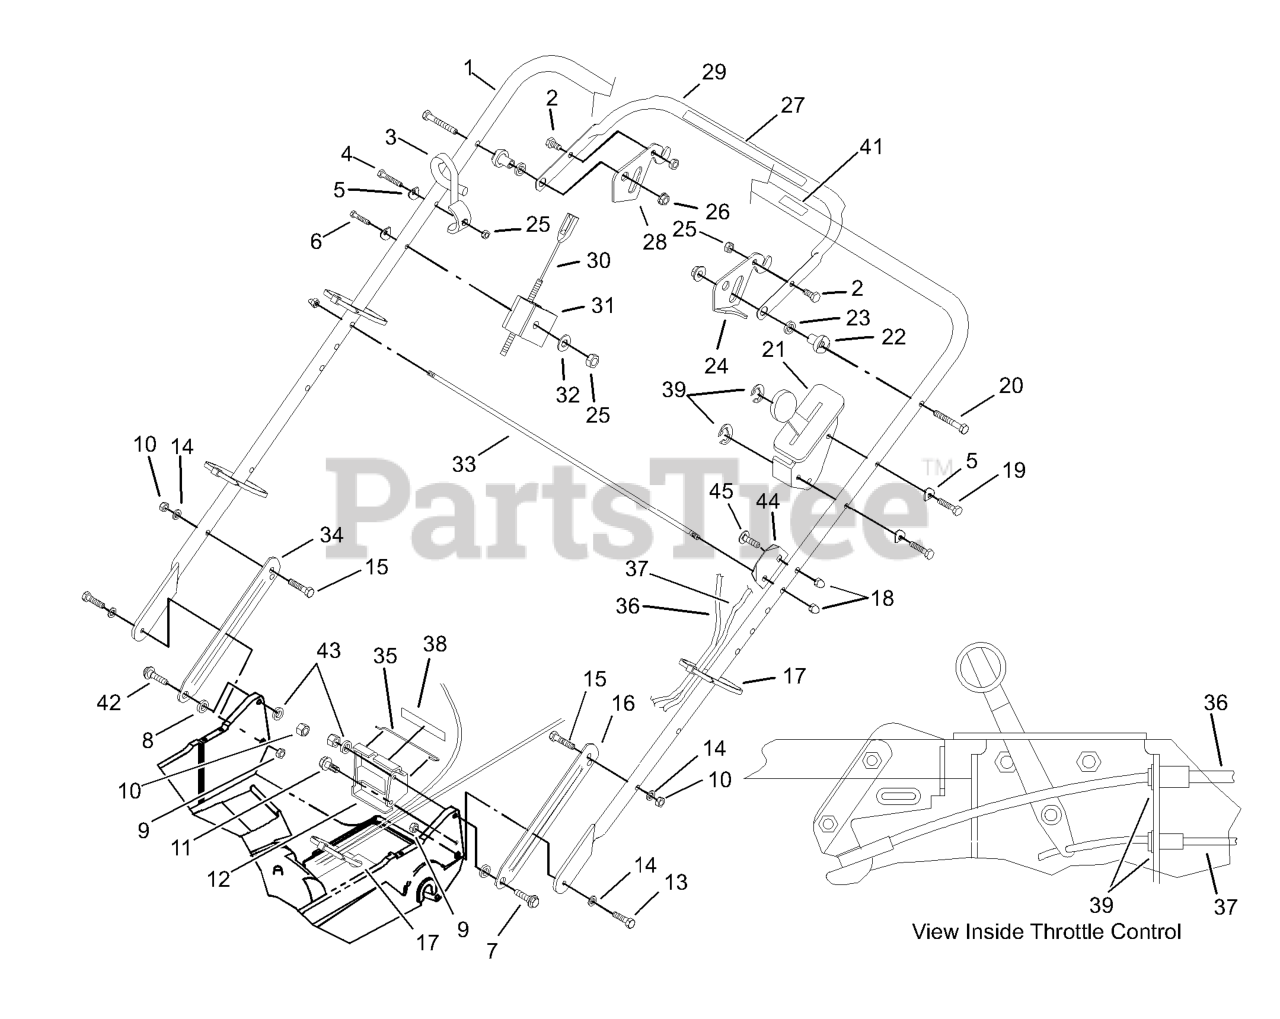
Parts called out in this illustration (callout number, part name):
2	SCREW-HH
3	GUIDE-ROPE
4	SCREW-HH
5	WASHER
6	SCREW-HH
7	SCREW-SHOULDER
8	SPACER
9	NUT-LOCK, NI
10	NUT-LOCK, NI
11	Screw-HWH 5/16-18 X 3/4 Tf
12	BRACKET-ADJUSTMENT, TRACT
13	SCREW-HH
14	WASHER-BELLEVILLE
15	SCREW-HH
17	TIE-CABLE
18	NUT-CAP
19	SCREW-HH
20	SCREW-HH
22	SPACER-SUPPORT
23	SPACER-NYLON
24	LEVER-CONTROL
25	NUT-LOCK, NI
26	NUT-LOCK, NI
28	LEVER-CONTROL
29	BAR-CONTROL
30	CABLE-BRAKE
31	SUPPORT-CABLE
32	WASHER-FLAT
33	ROD-SUPPORT, BAG
35	RETAINER-CABLE
36	CABLE-TRACTION
38	DECAL-POSITION, GEAR
41	DECAL-PROTECTION, HEARING
42	SCREW-SHOULDER
43	WASHER-PLAIN
45	SCREW-CARR
